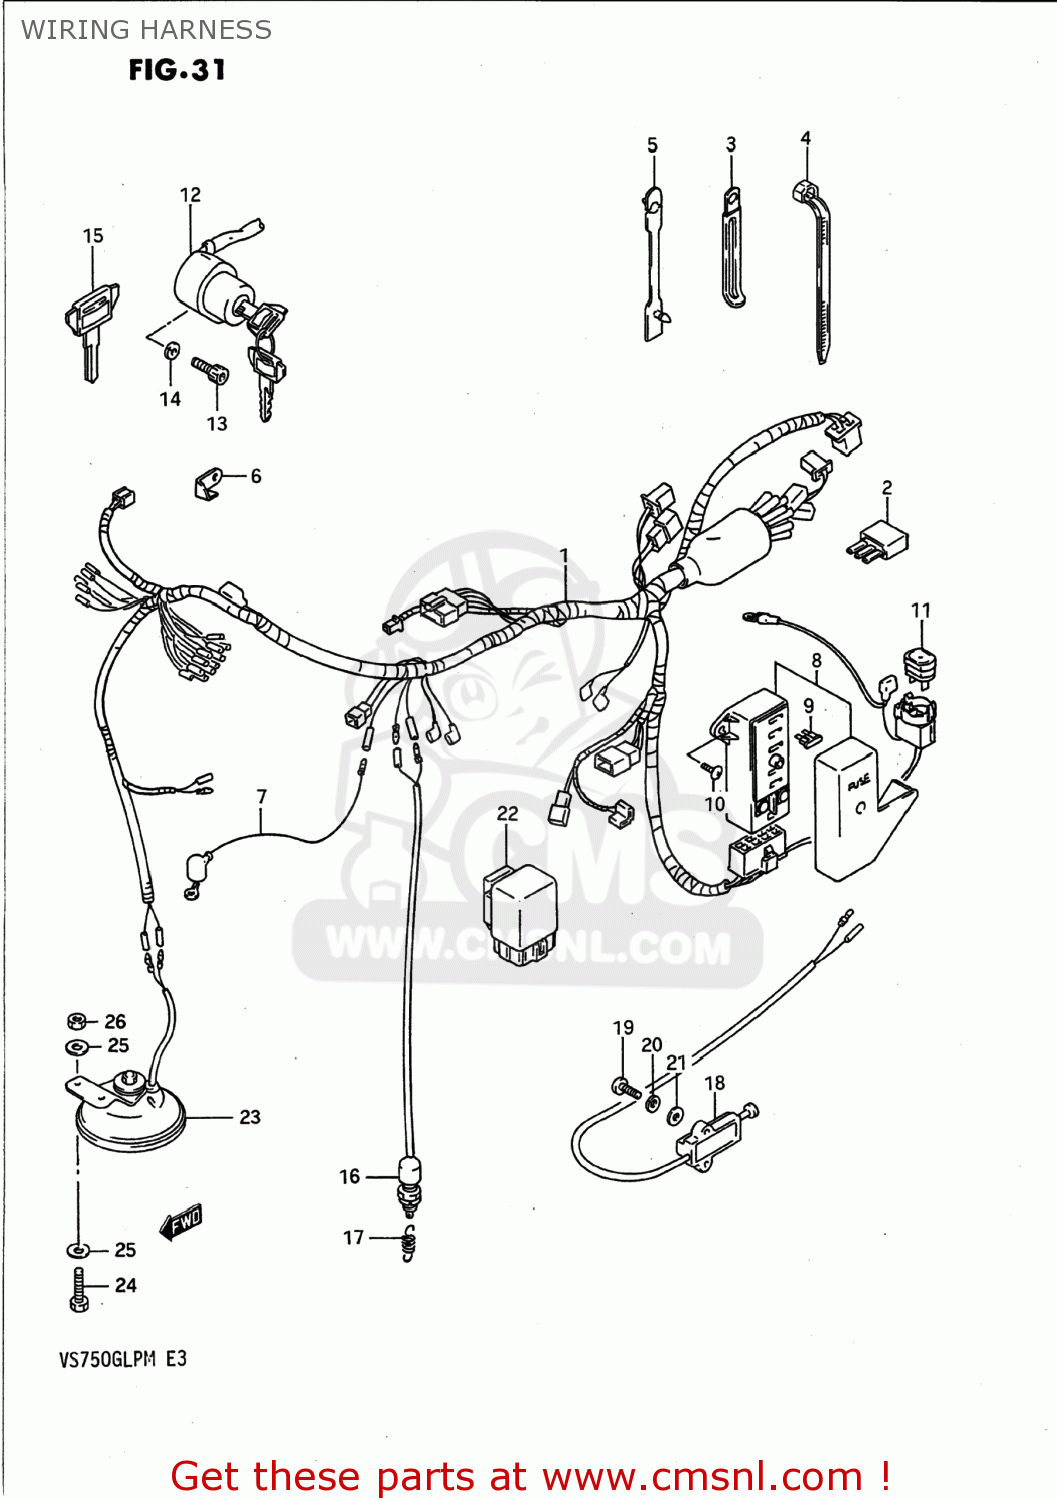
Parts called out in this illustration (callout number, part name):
1	HARNESS,WIRING
2	DIODE(STANLEY DE8804)
3	CLAMP
4	CLAMP(L:125)
5	CLAMP,L:88
6	PLATE,COUPLER HOLDER
7	WIRE,WATER TEMPERATURE GAUGE
8	BOX ASSY,FUSE
9	FUSE(10A)
10	SCREW
11	BREAKER ASSY,CIRCUT
12	SWITCH ASSEMBLY,IGNITION
13	BOLT
14	LOCK WASHER
15	KEY,BLANK(TYPE:C)
16	SWITCH ASSY,STOP LAMP
17	SPRING
18	SWITCH ASSEMBLY,SIDE STAND
19	SCREW
20	WASHER,LOCK
21	WASHER
22	RELAY ASSEMBLY
23	HORN ASSY
24	BOLT 6X30
25	WASHER
26	NUT 6MM
